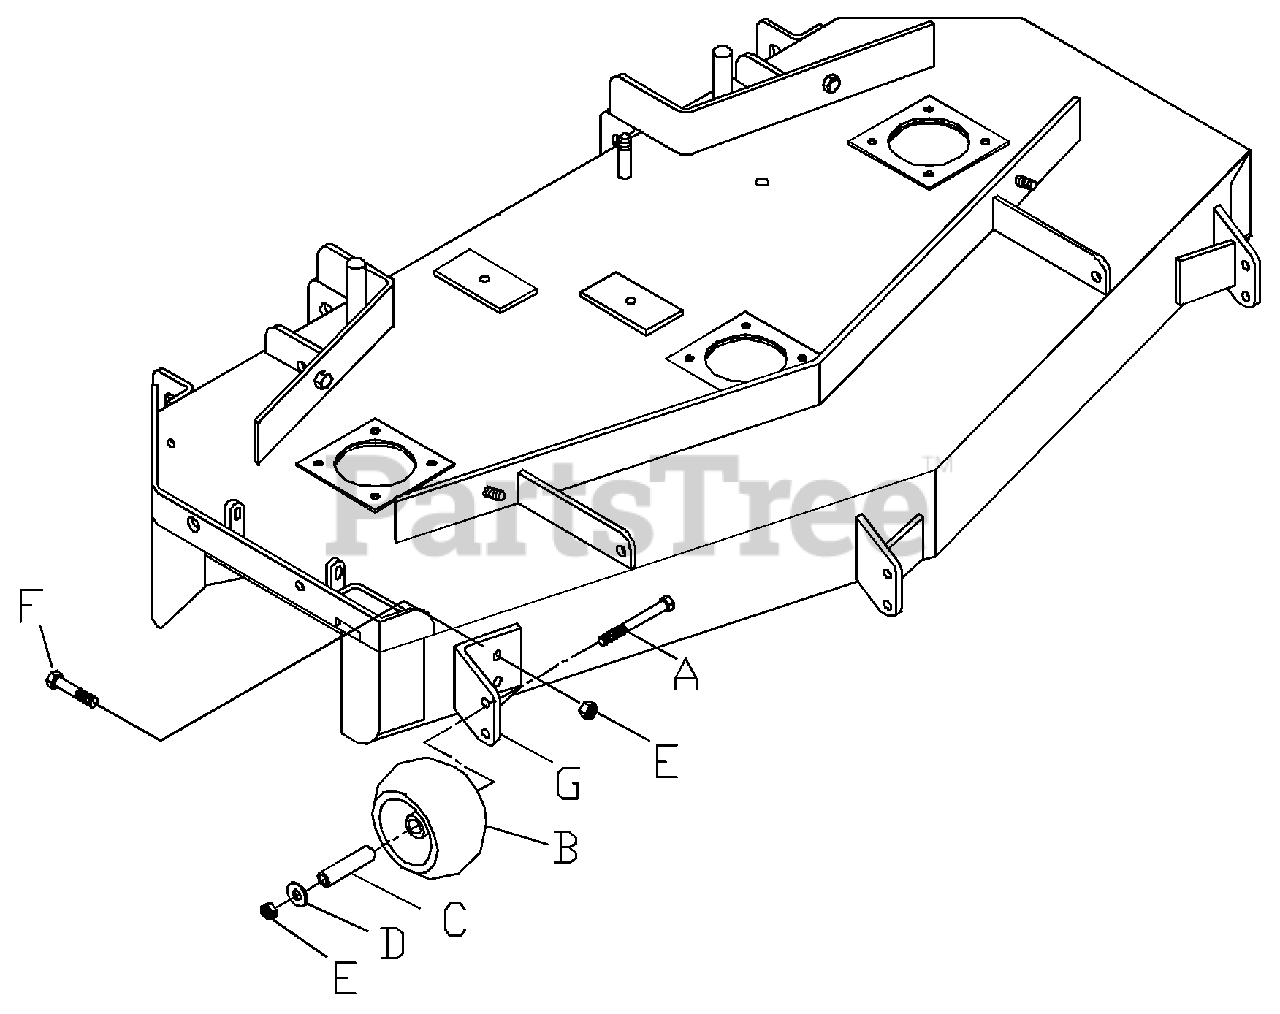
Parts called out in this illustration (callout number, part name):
A	HCS 3/8C X 3-1/2
B	ANTI-SCALP ROLLER
D	FW 3/8 STD.
E	NUT 3/8C CENTERLOCK
F	HCS 3/8C X 1-1/2
G	MOUNTING BRACKET
